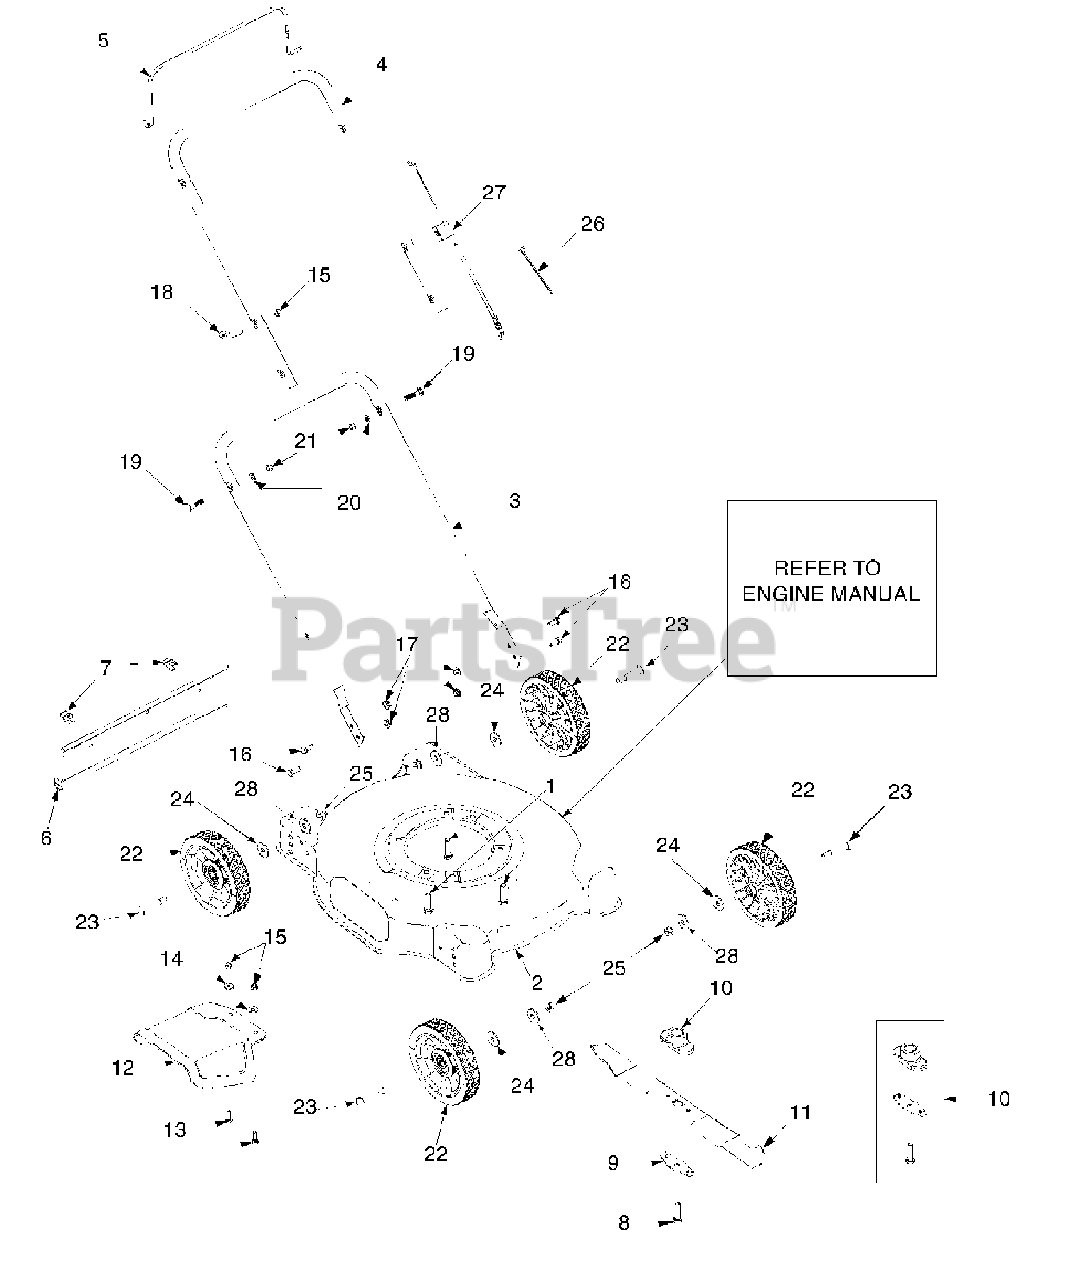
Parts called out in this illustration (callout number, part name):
1	Upper Handle
2	Control Handle
6	Handle Knob
7	Rope Guide
8	Carriage Bolt 5/16-18 x 2"
9	Shoulder Washer.320 ID x.930 OD
10	Wing Nut
11	Lower Handle
12	Control Cable 40"
13	Grass Bag
14	Grass Catcher Frame
15	Hairpin Clip
16	Grass Bag Door
18	Wire Rod
19	Trail Shield
20	Spacer.375 O.D. x.50 I.D. x 1.02"
21	Torsion Spring - RH
21	Torsion Spring - LH
22	Handle Bracket Assembly - RH
22	Handle Bracket Assembly - LH
23	Rear Wheel: 12 x 2.125
25	Hex Washer Screw 3/8-16 x 1.0
31	Rear Baffle - LH
32	Tap Screw 1/4-14 x.625.
33	Flange Lock Nut 3/8-16
34	Hex Carriage Screw 1/4-20
35	Handle Bracket Assembly - RH
35	Handle Bracket Assembly - LH
36	TT Screw 1/4-14 x.625
37	Hex Screw 3/8-16 x 0.75
39	Pivot Bar Assembly - RH
39	Pivot Bar Assembly - LH
40	Shoulder Screw
42	Rear Spring Lever
43	Spring Lever Grip
45	Wing Nut
46	Front Height Adjuster Assembly - RH
46	Front Height Adjuster Assembly - LH
47	Front Wheel: 8 x 2.125
49	Flange Lock Nut 3/8-16
50	Front Baffle
55	Blade Adapter
56	21" Mulching Blade
57	Blade Bell Support
58	Hex Cap Screw 3/8-24 x 1.5
59	Height Adjustment Plate
60	Knob
61	Pivot Bar Assembly - RH
61	Pivot Bar Assembly - LH
62	Spring Lever
64	Chute Door Pivot Rod
66	Hubcap
67	Tap Screw 1/4-20 x.500
68	Deluxe Bail Cover
69	Rear Baffle - RH
